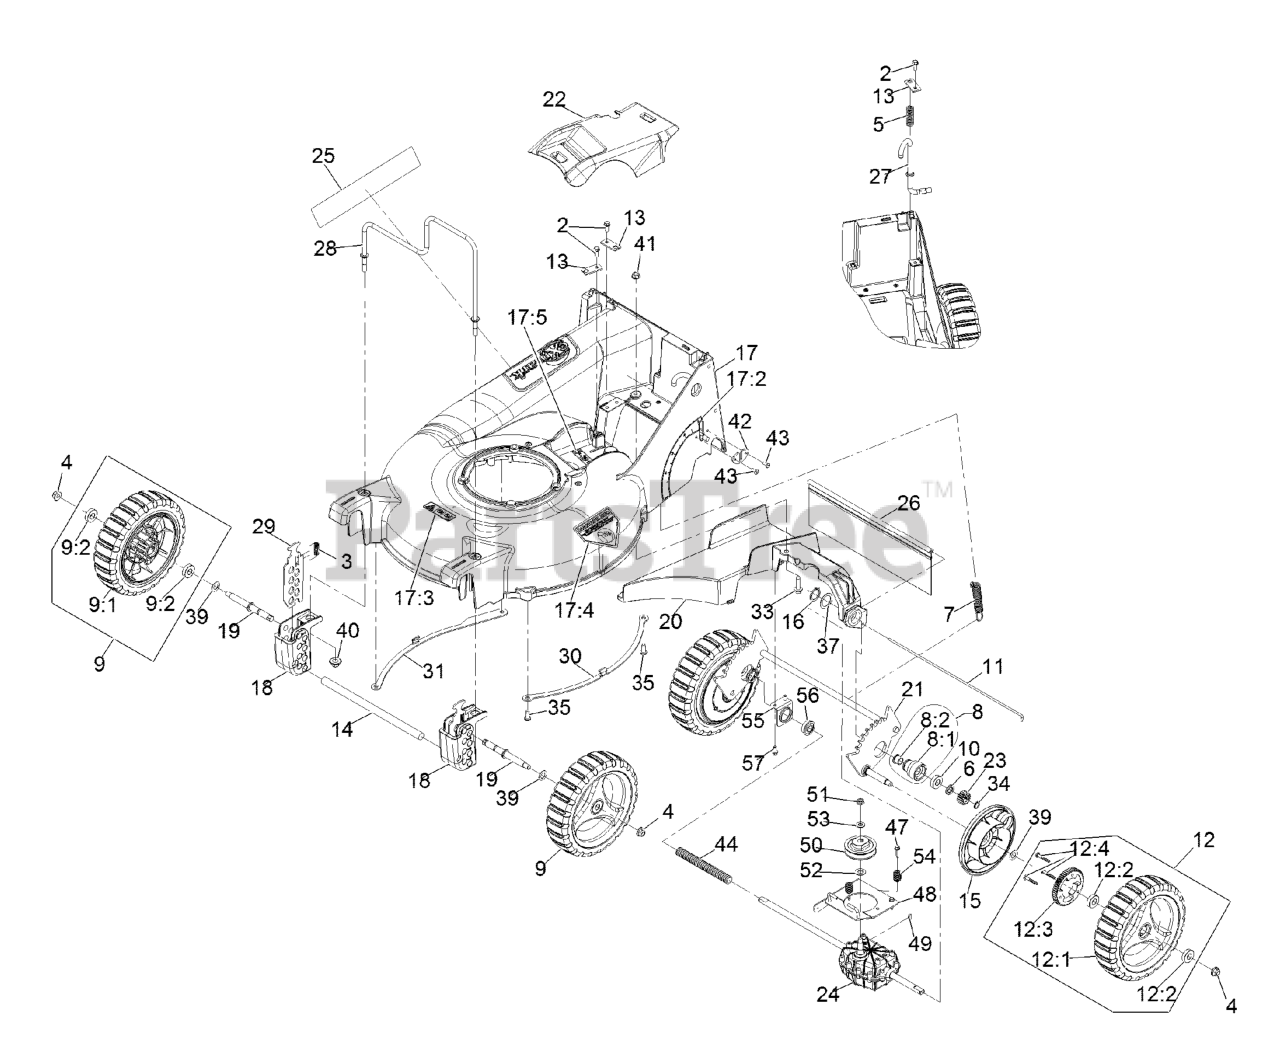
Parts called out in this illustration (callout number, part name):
2	SCREW-HWH
3	SPRING-COMPRESSION
4	NUT-HF, NI
5	SPRING-COMPRESSION
6	SPACER-BUSHING
7	SPRING-EXTENSION
8	HOUSING ASM
8:1	HOUSING-BEARING
8:2	BEARING-FLANGE
9	WHEEL ASM, 9" W/BEARINGS
9:1	WHEEL ASM, 9
9:2	BEARING-BALL
10	BEARING-BALL
11	ROD,SHIELD
12	WHEEL ASM, 9 W/GEAR
12:1	WHEEL ASM, 9
12:2	BEARING-BALL
12:3	GEAR-WHEEL, 52T
12:4	STUD-DRIVE
13	BRACKET,MOUNT
14	ROD,BUMPER
15	COVER,GEAR
16	RING-RETAINING
17	DECK W/DECALS
17:2	DECAL-HEIGHT OF CUT
17:3	DECAL-WARNING, BLADE
17:4	DECAL-DANGER
17:5	DECAL-DANGER
18	BLOCK,FRONT QUADRANT
19	AXLE-WHEEL
20	BRACKET-TRANSMISSION AND
21	WLD,REAR AXLE P21
22	COVER,BELT
23	GEAR-PINION, 15T
24	TRANSMISSION-HD, 4.5/1
25	DECAL-COMM 21 X-SERIES
26	SHIELD-TRAILING P21
27	ROD-HEIGHT ADJ P21
28	GUARD,ENGINE
29	PLATE, FRONT HEIGHT
33	SCREW-HWHTF
34	RING-RETAINING
35	SCREW-BHTF
39	WASHER-PLAIN
40	Nut-Nyloc 3/8-16 Flg
41	NUT-HF, NI
42	PLATE,WEAR
43	RIVET-BLIND
44	COVER-SHAFT-DRIVE
47	SCREW-SPECIAL
48	TRANSMISSION PLATE ASM
49	KEY-WOODRUFF
51	NUT-HEX
52	WASHER-THRUST
53	WASHER-FLAT
54	SPRING,COMPRESSION
55	MOUNT-BEARING
56	BEARING-BALL
57	SCREW-HWH
